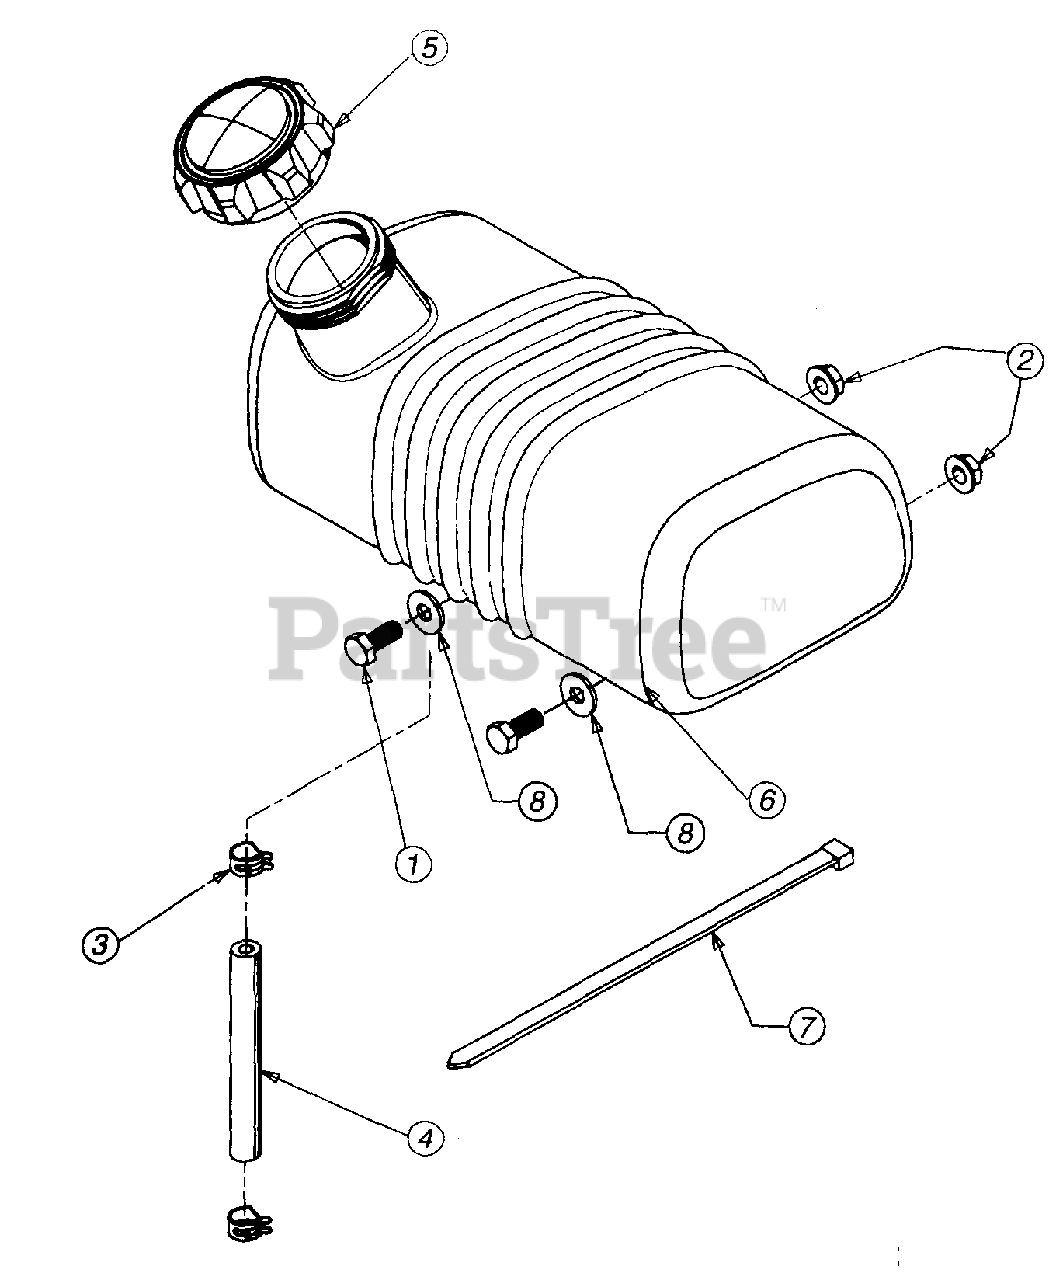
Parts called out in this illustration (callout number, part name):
1	SCREW-HEX
2	NUT-HEX LOCK FLANGE
3	CLAMP-HOSE
4	HOSE-FUEL LINE 9"
5	CAP-FUEL
6	TANK-FUEL 1 GALLON
7	CABLE TIE
8	FLAT WASHER
